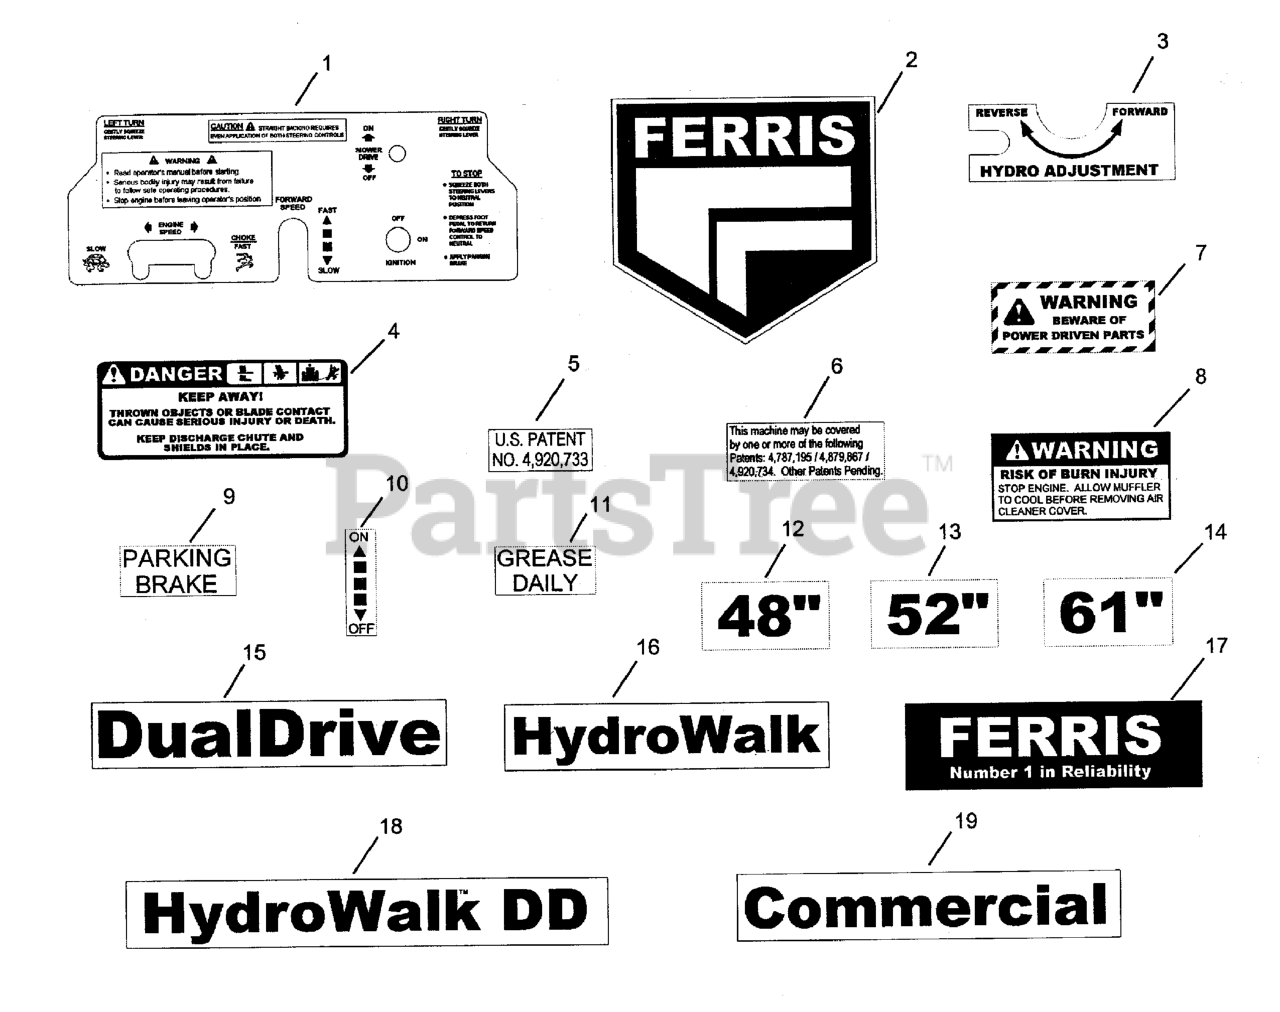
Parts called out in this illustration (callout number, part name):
1	DECAL, Operation
2	DECAL, Ferris Logo, 10-3/4"
3	DECAL, Hydro Adjustment
4	DECAL, DANGER DO NOT OPERATE W/O DEFLECT
5	DECAL, U.S. Patent
6	DECAL, Patent
7	DECAL, Warning
8	DECAL, Warning-Burn
9	DECAL, Parking Brake
10	DECAL, PTO Switch
11	DECAL, Grease Daily
12	DECAL, 48
13	DECAL, 52
14	DECAL, 61"
15	DECAL, Dual Drive
16	DECAL, HydroWalk, Word
17	DECAL, FERRIS TEXT & LOGO
18	DECAL, HYDROWALK DD
19	DECAL, Commercial
